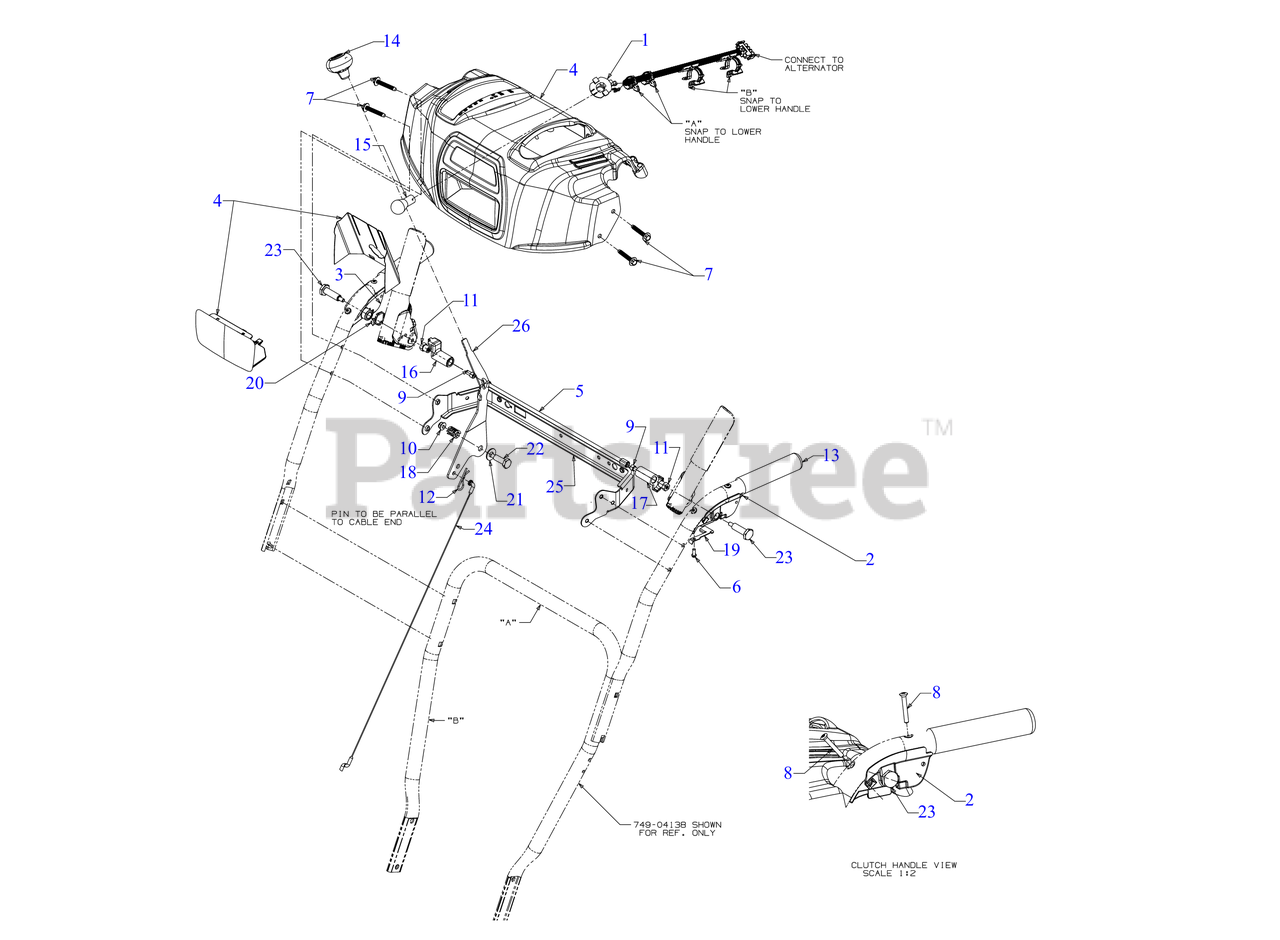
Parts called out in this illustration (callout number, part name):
1	LIGHT HARNESS
2	CLUTCH LOCK HANDLE ASSEMBLY (LH)
3	CLUTCH LOCK HANDLE ASSEMBLY (RH)
4	HANDLE PANEL ASSEMBLY
6	SCREW #8-16 x .50
7	SCREW 1/4-20 x 1.625
8	SCREW #10-24 x 1.375
9	SCREW 1/4-20 x .50
10	FLANGE LOCK NUT
11	HEX NUT W/PATCH
12	INTERNAL COTTER PIN
14	SHIFT KNOB
15	LAMP-12 VOLT
17	CLUTCH LOCK CAM
18	COMPRESSION SPRING
19	CLUTCH SPRING
20	TORSION SPRING
21	FLAT WASHER .40X.88X.060
22	SHOULDER SCREW
23	SHOULDER SCREW .437 x 1.345 1/4-20
24	SPEED SELECTOR CABLE (PLASTIC)
25	HANDLE SUPPORT BRACKET (POWDER BLACK)
